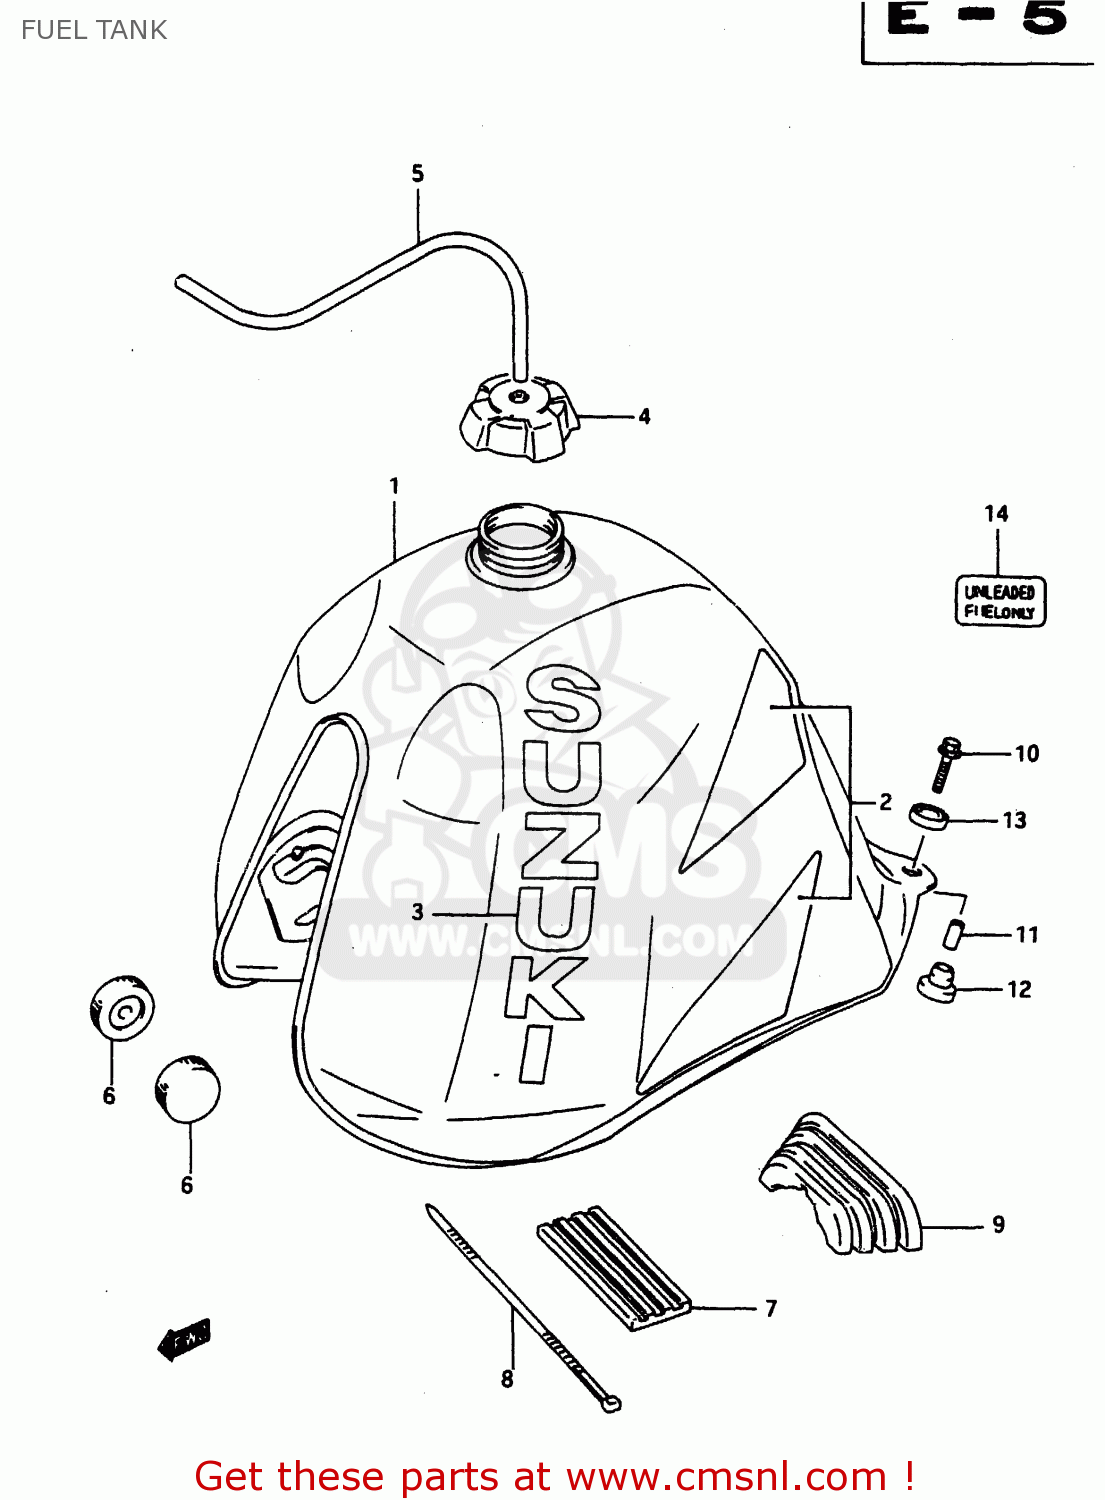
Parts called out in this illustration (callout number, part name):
1	TANK ASSY, FUEL
2	TAPE SET, FUEL TANK
3	EMBLEM SET, FUEL TANK
4	CAP ASSY,FUEL TANK
5	HOSE
6	CUSHION
7	CUSHION,FUEL TANK UPR FR
8	CLAMP
9	CUSHION,FUEL TANK RR
10	BOLT
11	SPACER
12	CUSHION
13	CUSHION
14	LABEL,FUEL CAUTION
